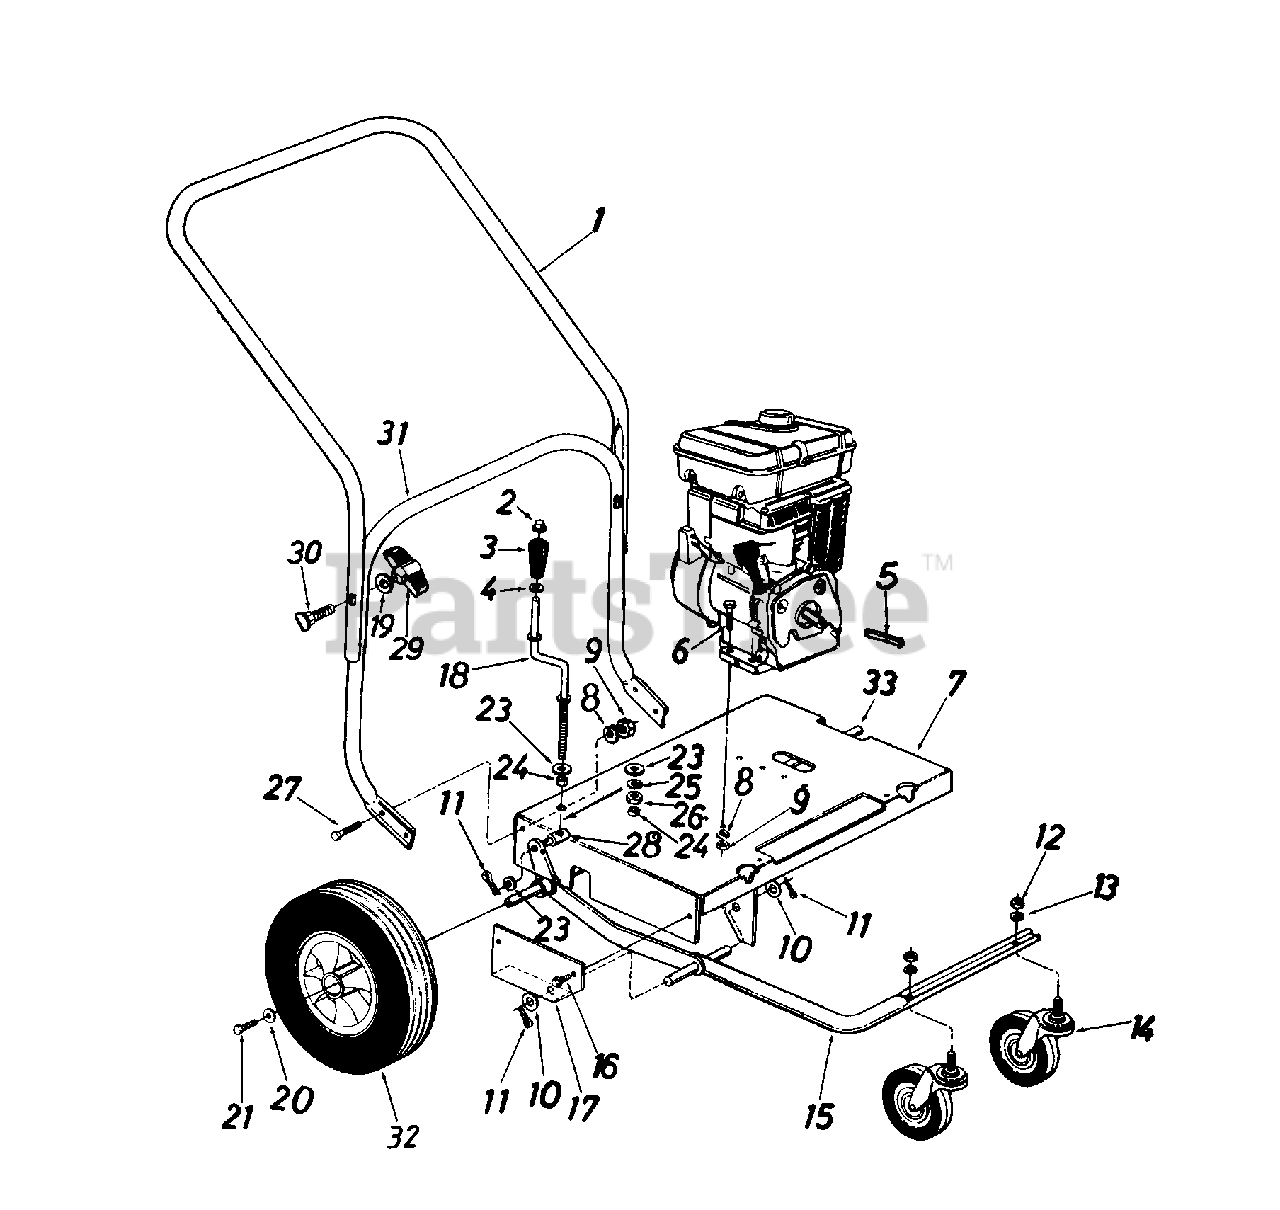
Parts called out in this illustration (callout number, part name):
2	Push Nut 3/8" Rod
3	Crank Knob
4	Fl-Wash. .385" I.D. x .62"
5	Sq. Key 1/4" x 2.0" Lg.
6	Hex Bolt 5/16-18 x 1.50" Lg.
9	Hex Nut 5/16-18 Thd.
10	Fl-Wash. .63" I.D. x 1.25"
11	Cotter Pin 1/18" Dia. x 1.0"
12	Hex Nut 1/2-13 Thd.
13	L-Wash. 1/2" I.D.
14	Swivel Caster Wheel 5" Dia. x 1.25"
19	Saddle Wash. .32" I.D. x .93"
20	Fl-Wash. .34" I.D. x .87" O.D.
21	Hex L-Bolt 5/16-24 x .64" Lg.
23	Fl-Wash. .38" I.D. x .57"
24	Spacer .382" I.D. x .50" x .180" Lg.
25	L-Wash. 3/8" I.D.
26	Hex Nut 3/8-8 Thd.
27	Hex Nut Bolt 5/16-18 x .75" Lg.
28	Ferrule
29	Handle Knob
30	Carriage Knob
33	Rear Axle
